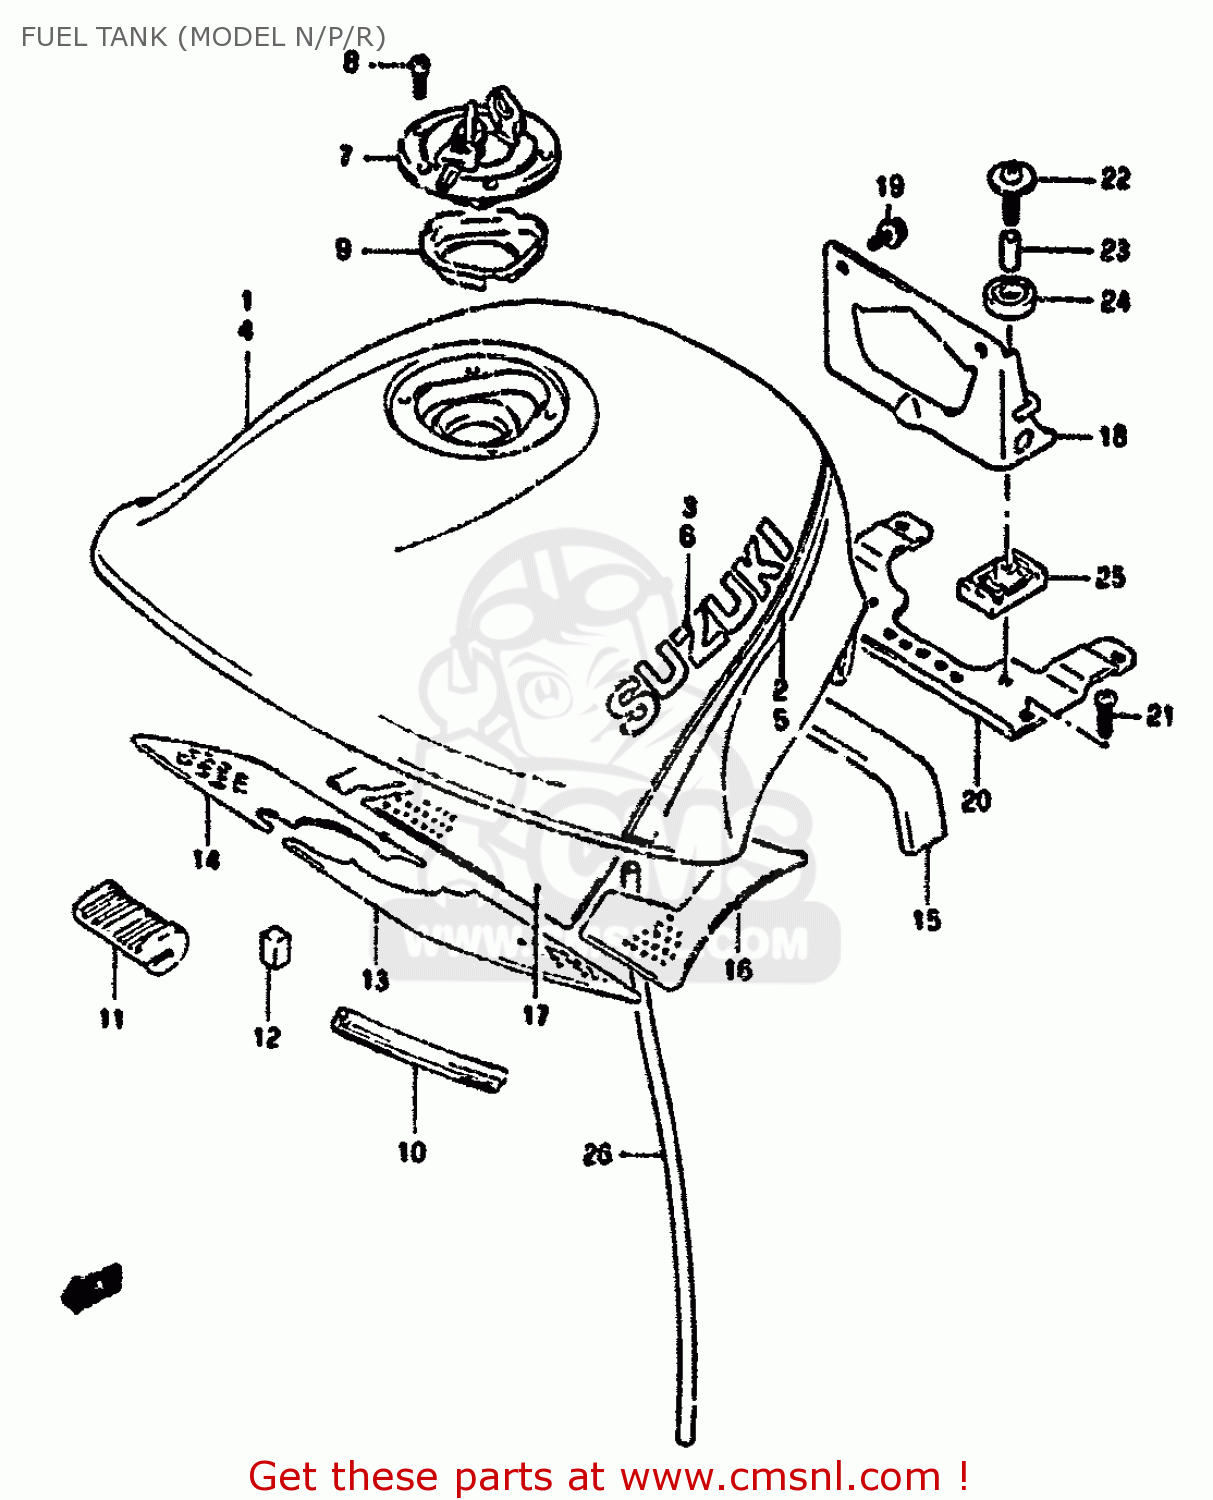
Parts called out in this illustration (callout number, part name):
1	TANK ASSY,FUEL
2	TAPE,FUEL TANK STRIPE
3	EMBLEM (GOLD)
4	TANK ASSY,FUEL
5	STRIPE TAPE,TN
6	EMBLEM (GRAY)
7	CAP SET,FUEL TANK
8	BOLT(5X10)
9	COVER,FUEL TANK INLET
10	MOLDING,FUEL TANK
11	CUSHION,FUEL TANK FR
12	CUSHION,FUEL TANK SIDE
13	HEATSHIELD,FUEL TANK FR,L
14	HEAT SHIELD,FUEL TANK
15	HEAT SHIELD,FUEL TANK
16	HEATSHIELD,FUEL TANK RR,L
17	HEAT SHIELD,FUEL TANK
18	BRACKET COMP,FUEL TANK
19	SCREW(6X16)
20	BRACKET,FUEL TANK RR LOW
21	SCREW
22	BOLT L:35,WITH WASHER
23	SPACER (6.4X9X21.5)
24	CUSHION
25	CUSHION
26	HOSE (7X10.2X1000)
